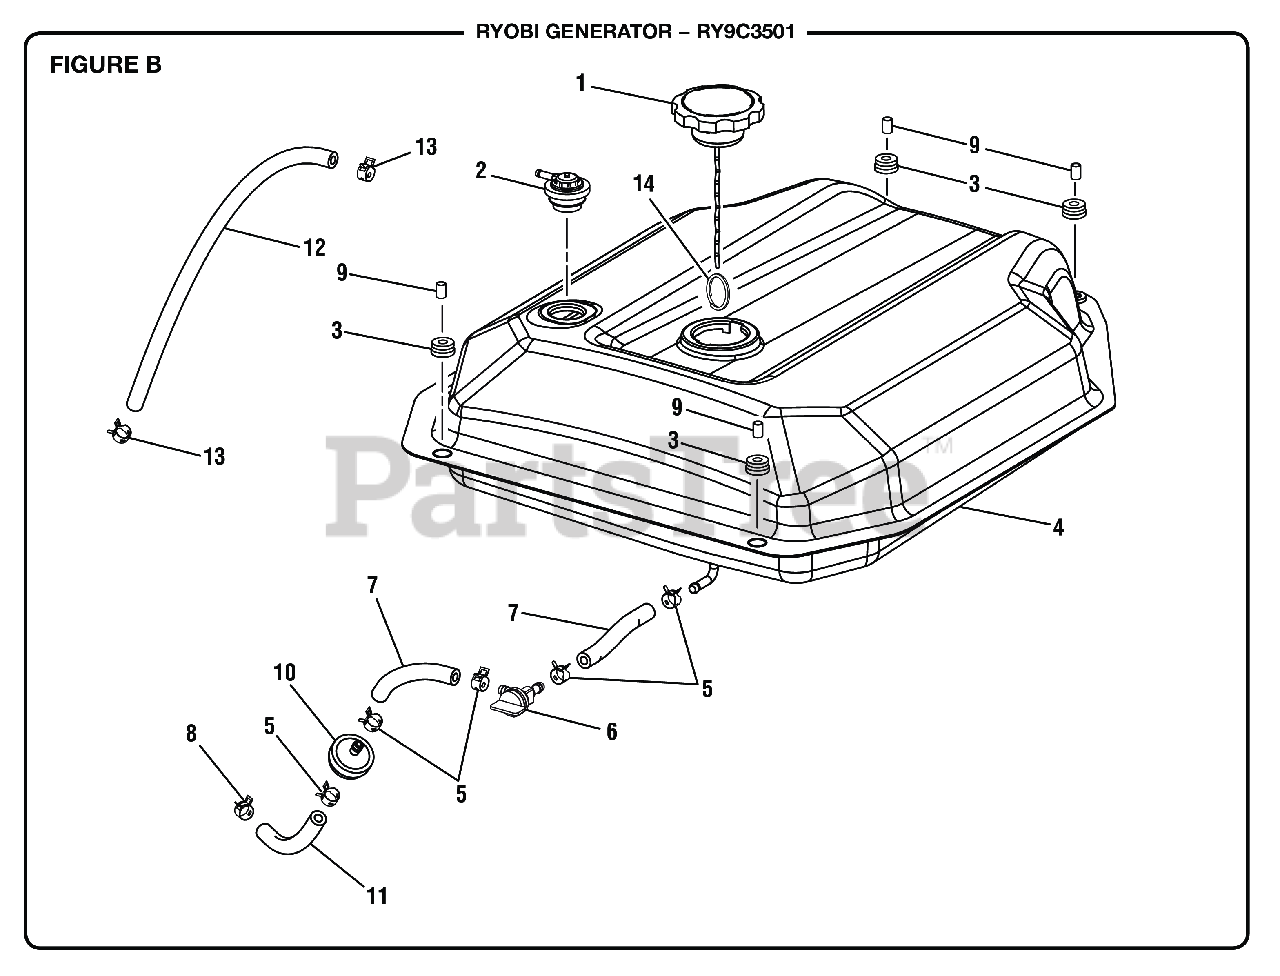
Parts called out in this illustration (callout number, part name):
1	Fuel Cap Assembly
2	Fuel Tank Vapor Vent
3	Bushing (Fuel Tank Isolator)
4	Fuel Tank
5	Fuel Line Clamp (CTL-6.5)
6	Fuel Shut Off Valve
7	Fuel Line (90 mm)
8	Vapor Line Clamp (5/16 in.)
9	Spacer (Fuel Tank Isolator)
10	Fuel Filter Inline (1/4 in.)
11	Fuel Hose (150 mm)
12	Vapor Hose (330 mm)
13	Fuel Line Clamp (7/16 in., BM903611)
14	Ring Clip
